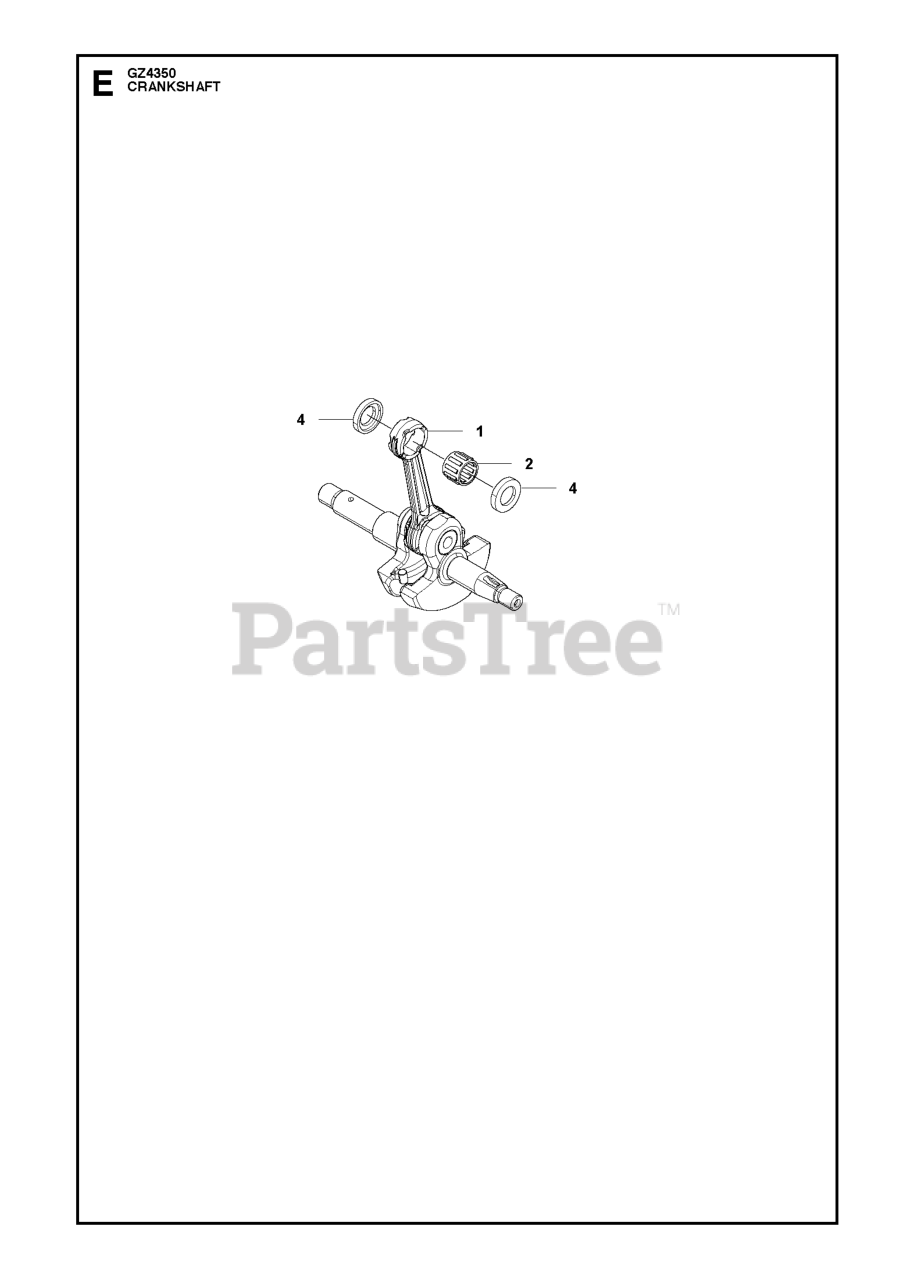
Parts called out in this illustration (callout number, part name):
1	CRANKSHAFT ASSY
2	NEEDLE BEARING
4	WASHER
